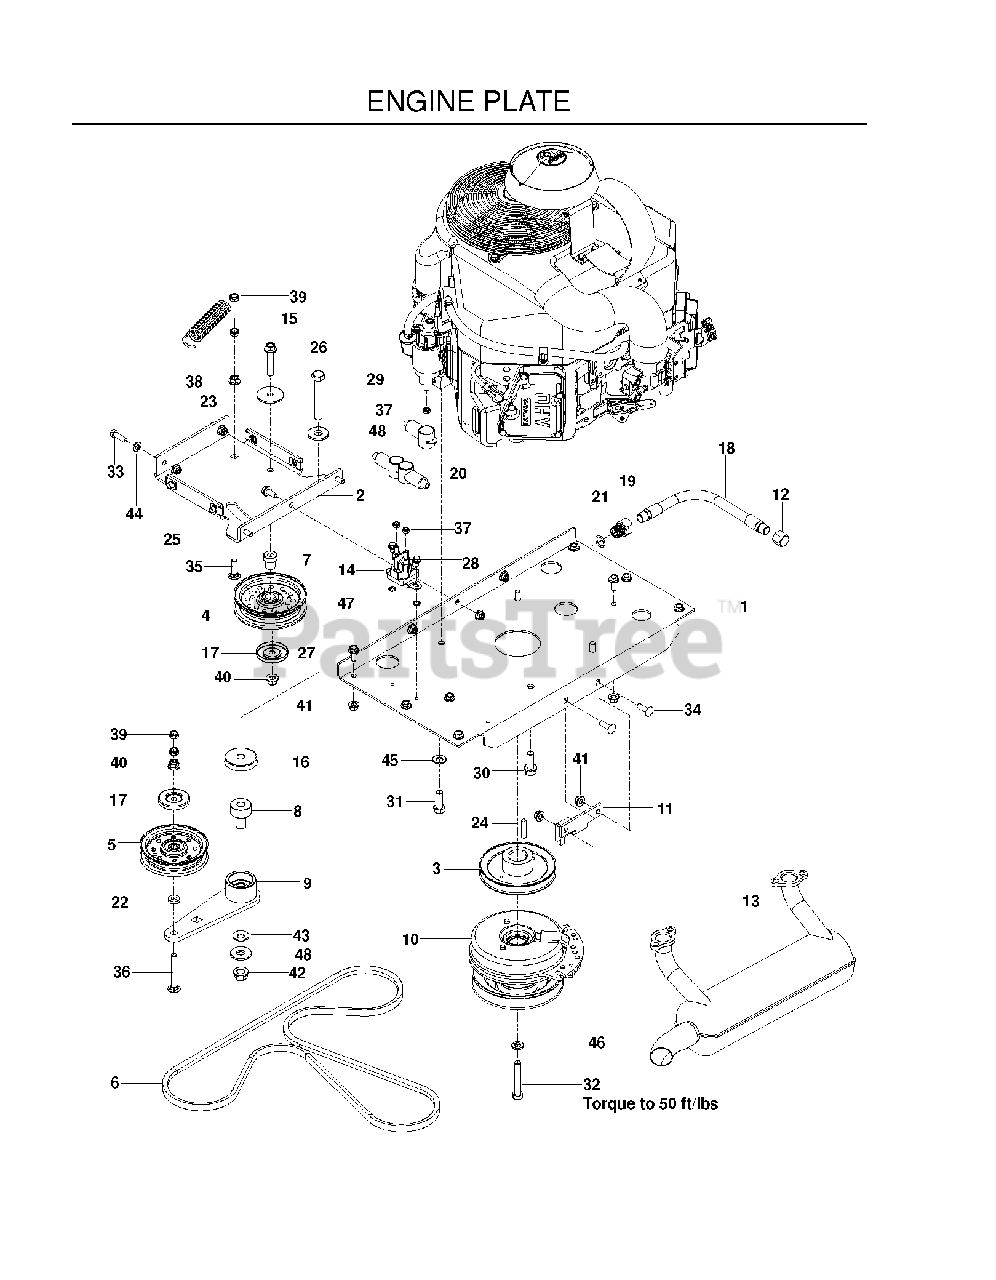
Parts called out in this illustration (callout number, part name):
2	PLATE, IDLER, BLK
3	PULLEY, V, 1.125 BORE
4	IDLER PULLEY
6	BELT, HYDRO, 3400
7	PIVOT, IDLER
8	PIVOT, BEARING
9	ARM, IDLER, STEEL, W/BGS
10	CLUTCH, 200 FT-LB
12	DRAIN CAP
13	MUFFLER, 26HP KAW FX651V-730V
14	SOLENOID
15	SPRING, PUMP
16	SHIELD, DUST
17	DUST SHIELD
18	OIL DRAIN HOSE
19	ADAPTER, OIL DRAIN
20	INSULATOR
22	WASHER 3/8 X 3/4 X .187 TK
23	WASHER, 3/8 SPEC
24	KEY, 1/4 SQ X 1 1/4
25	U-CLIP 5/16-18 NUT RETAINER
26	HHFS 3/8-16 X 2.0 GD 5
27	HHFS 5/16-18 X 3/4
28	HWST 1/4C X 3/8
29	HCS 1/2C X 3 1/4
30	HCS 3/8C X 1 SERRATED HEAD
31	HCS 3/8C X 1
32	BOLT 7/16F X 2 1/2
33	HCS 5/16C X 1
34	RHSSNB 5/16C X 1.0
35	RHSNB 3/8-16 X 1-1/4
36	RHSNB 3/8-16 X 2.75
37	JAM NUT 1/4C
38	NUT 3/8C WHIZ
39	NUT HEX 3/8-16 NYLON, THIN
40	NUT 3/8-16 HEX FLG NYLOC ZD
41	5/16-18 NYLOC FLANGE NUT
42	NUT, 1/2-13 HEX FLG NYLOC ZD
43	CONTACT BELLSPR 1/2
44	FLAT WASHER 5/16 SAE
45	WASHER, 3/8 DISC SPRING SPEC
46	WASHER 7/16 LOCK
47	WASHER 1/4 INT TOOTH
48	WASH USS FLAT 1/2
